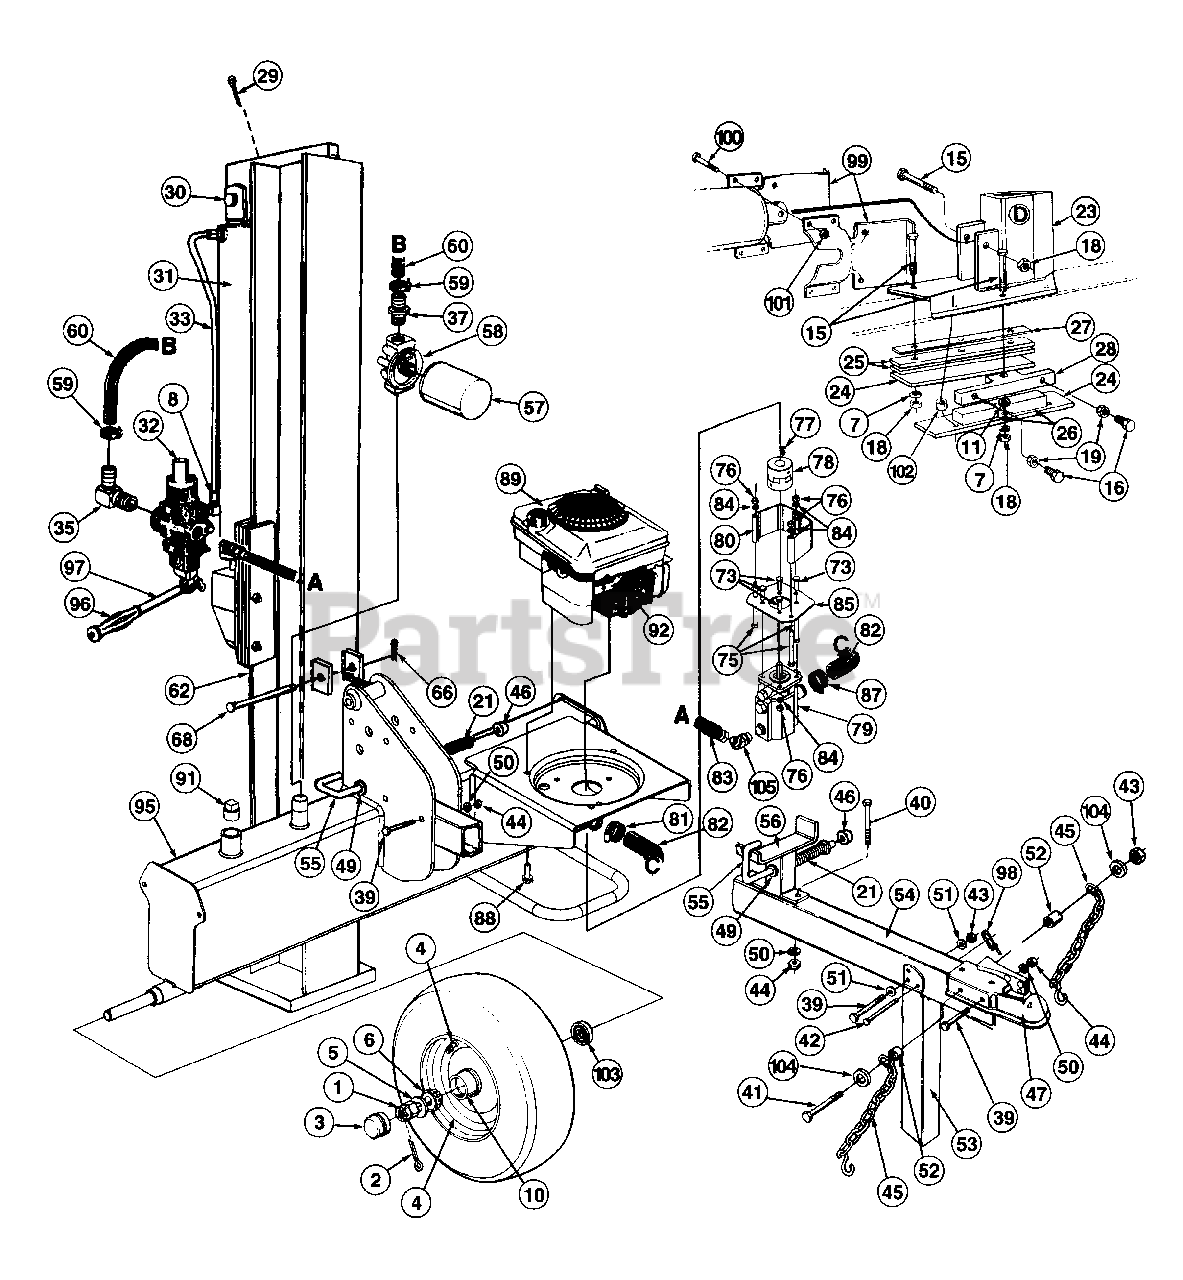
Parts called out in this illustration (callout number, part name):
1	Slotted Nut 3/4-16 Thd.
2	Cotter Pin 5/32" Dia. x 1-1/4" Lg.
3	Hub Cap
5	Fl-Wash. .76" I.D. x 1.5" O.D.
6	Bearing Cone
7	L-Wash. 1/2" I.D.
8	90ø Solid Male Adapter
10	Bearing Cup
11	Fl-Wash. .531" I.D. x .94" O.D.
15	Hex Bolt 1/2-20 x 2.75" Lg. (Grade 8)
16	Hex Bolt 3/8-24 x 1.5" Lg.
18	Hex L-Nut 1/2-20 Thd.
19	Hex Jam Nut 3/8-24 Thd.(Grade 5)
21	Comp. Spring 4" Lg.
26	Adjustable Gib
29	External Cotter Pin
30	Cylinder Mounting Pin
33	Metal Pressure Tube
35	Return Elbow
37	3/4" Hose Barb.
39	Hex Bolt 3/8-16 x 3" Lg.
40	Hex Bolt 3/8-16 x 4" Lg.
41	Hex Bolt 3/8-16 x 4" Lg. (Grade 5)
42	Clevis Pin 5/16 x 2.5" Lg.
43	Hex L-Nut 3/8-16 Thd.
44	Hex Nut 3/8-16 Thd.
45	Chain--Tow Hitch
46	Push Cap
47	Hitch Coupler
49	Fl-Wash. .635" I.D. x .93" O.D.
50	L-Wash. 3/8" I.D.
51	Fl-Wash. .406" I.D. x .75" O.D.
52	Spacer 3/8" I.D. x .625" O.D.
55	Locking Rod
57	Filter Element
58	Filter Head
59	Hose Clamp 5/8"
60	Return Hose 3/4" I.D. x 44" Lg.
62	Vertical Beam Ass'y.
66	Cotter Pin 1/8" Dia.
68	Hinge Pin 1/2 x 4.8" Lg.
73	Hex Bolt 5/16-24 x 1" Lg.
75	Hex Bolt 5/16-24 x 3.25" Lg.
76	Hex Nut 5/16-24 Thd.
77	Sq.-Key 3/16" x .75"
78	Flexible Coupling
79	Gear Pump
80	Coupling Shield
81	Hose Clamp
82	Suction Hose
83	High Pressure Hydraulic Hose
84	L-Wash. 5/16" I.D.
88	Hex Wash Hd. TT-Tap Scr. 3/8-16 x 1" Lg.
89	Engine
91	L-Vent Pipe Plug
92	Spark Plug Boot
97	Control Handle
98	Spring Pin
101	Hex L-Nut 3/8-16 Thd.
102	Spacer 1/2" I.D. x .68" Lg.
103	Bearing Seal Only
104	Fl-Wash. 3/8" I.D. x .87" O.D.
105	45ø Elbow
